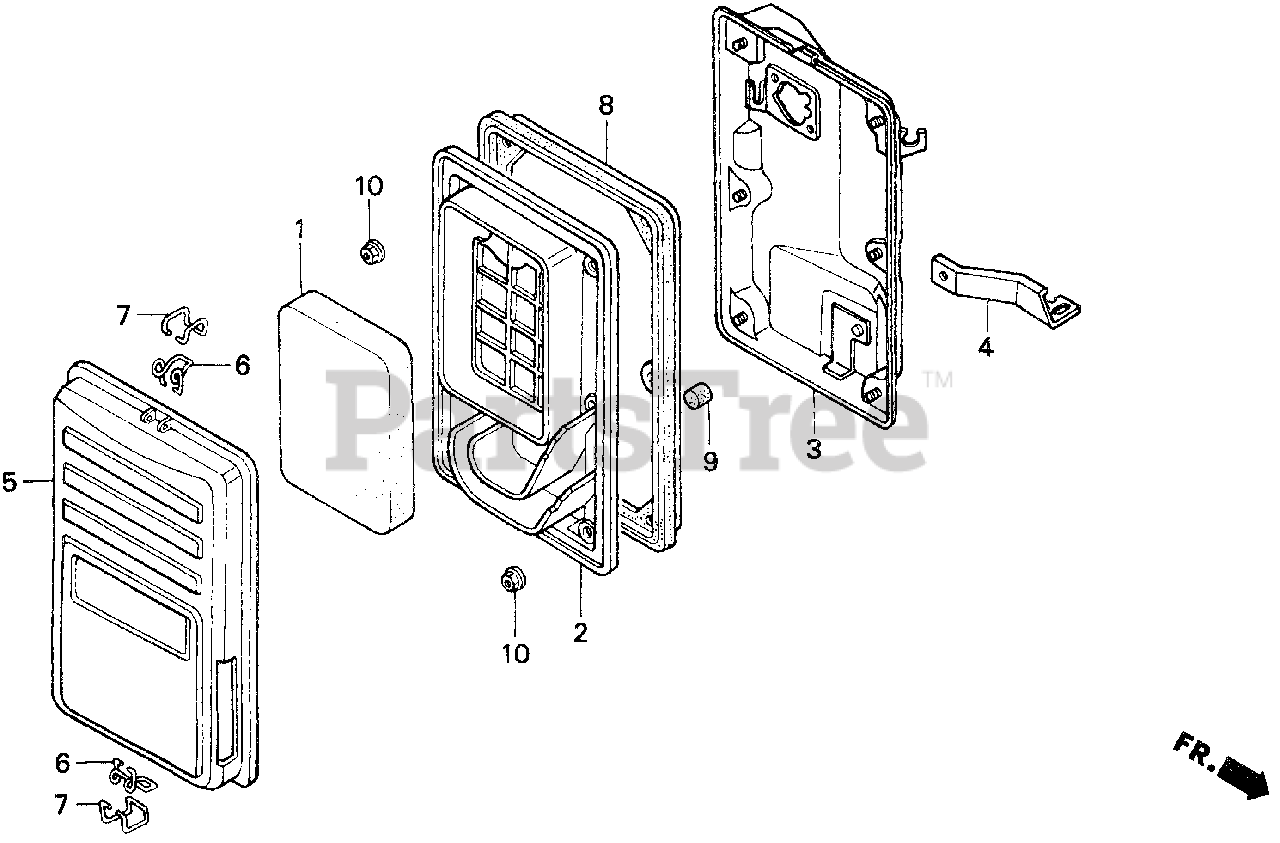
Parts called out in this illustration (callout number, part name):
1	ELEMENT, AIR CLEANER
2	SEPARATOR, AIR CLEANER
3	HOUSING, AIR CLEANER
4	STAY, AIR CLEANER
5	COVER, AIR CLEANER
6	CLIP A, AIR CLEANER WIRE
7	CLIP B, AIR CLEANER WIRE
8	SEAL, AIR CLEANER
9	FILTER, DRAIN TUBE
10	NUT, FLANGE (5MM)
